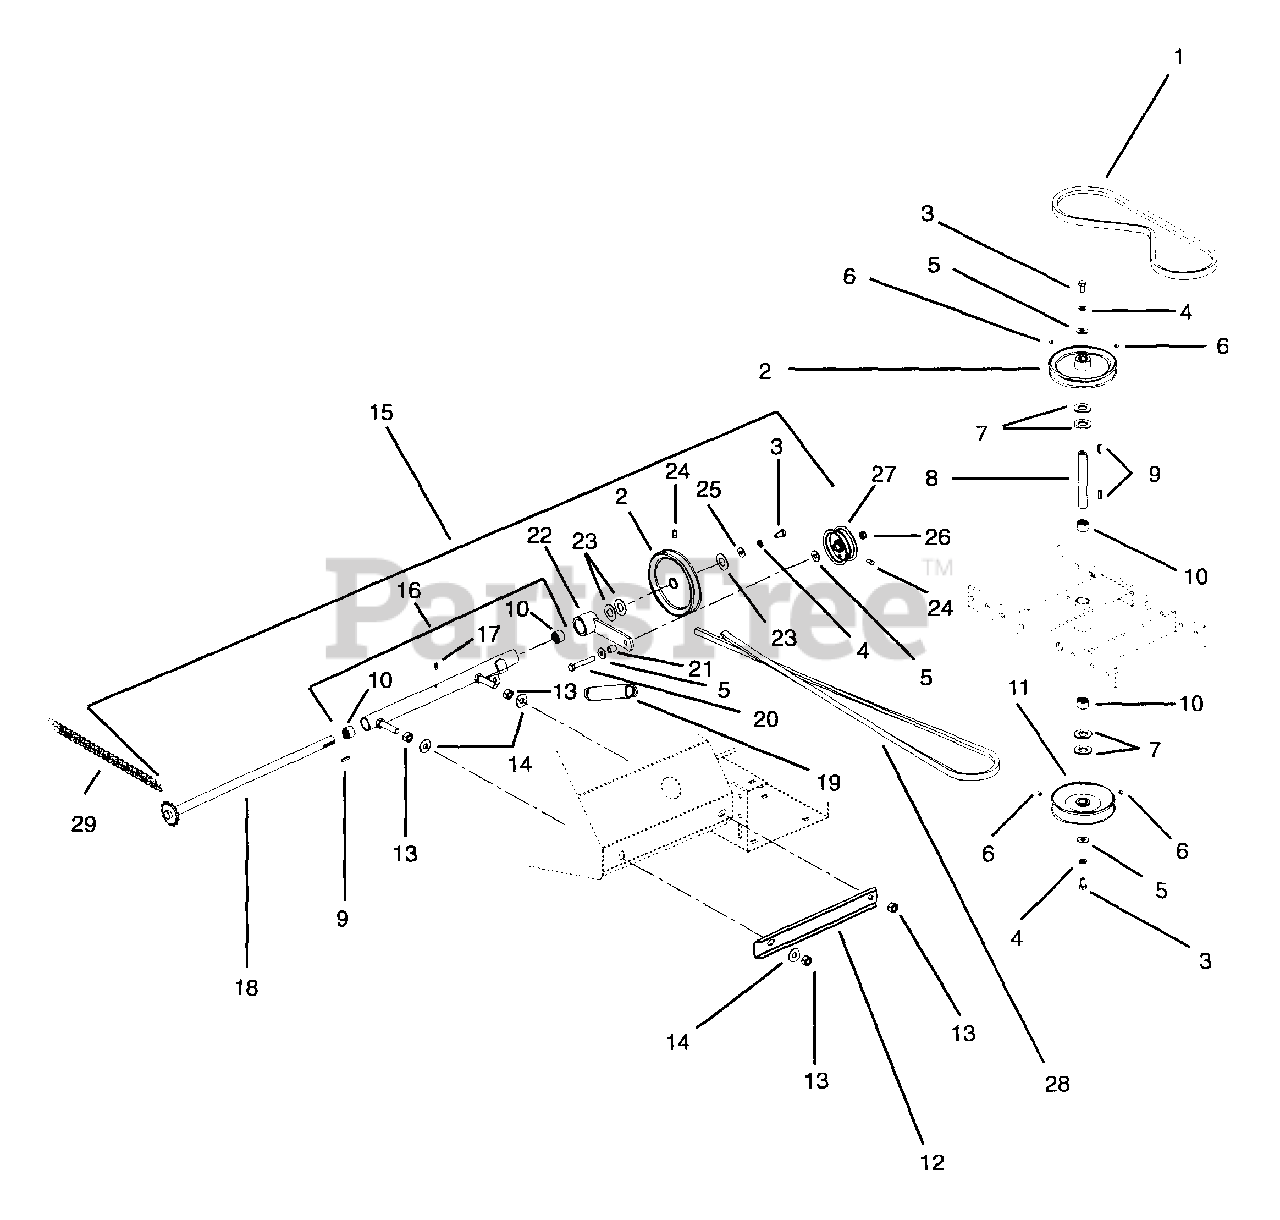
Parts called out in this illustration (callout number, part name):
2	PULLEY & HUB
3	@BLT-HEX .38-16X.75 GR5 YWZC
4	@WSHR-LK .38X.094 REG YWZC
5	@WSHR-FL-STL.438X1.00X.083 YWZ
6	SELF TAPPING SCREW 5/16-18
7	WASHER 13/16 X 1-1/2
9	KEY SQUARE
10	NEEDLE BEARING
11	PULLEY & HUB ASSEMBLY
12	SUPPORT BRACKET
13	NUT 1/2-13 LT HEX
15	JACKSHAFT HOUSING ASSEMBLY
16	JACKSHAFT HOUSING & BEARINGS
17	GREASE FITTING
18	JACKSHAFT & SPROCKET ASSEMBLY
20	@BLT-HEX .38-16X2.50 GR5 YWZC
22	IDLER ARM
23	FLAT WASHER
24	SCR-SET .32-18X.50 SQHCUP OH
25	@WSHR-FL-STL.38X.875X.083 YWZC
26	@NUT-LK-CTR .38-16 YWZC
27	IDLER PULLEY
29	ROLLER CHAIN
